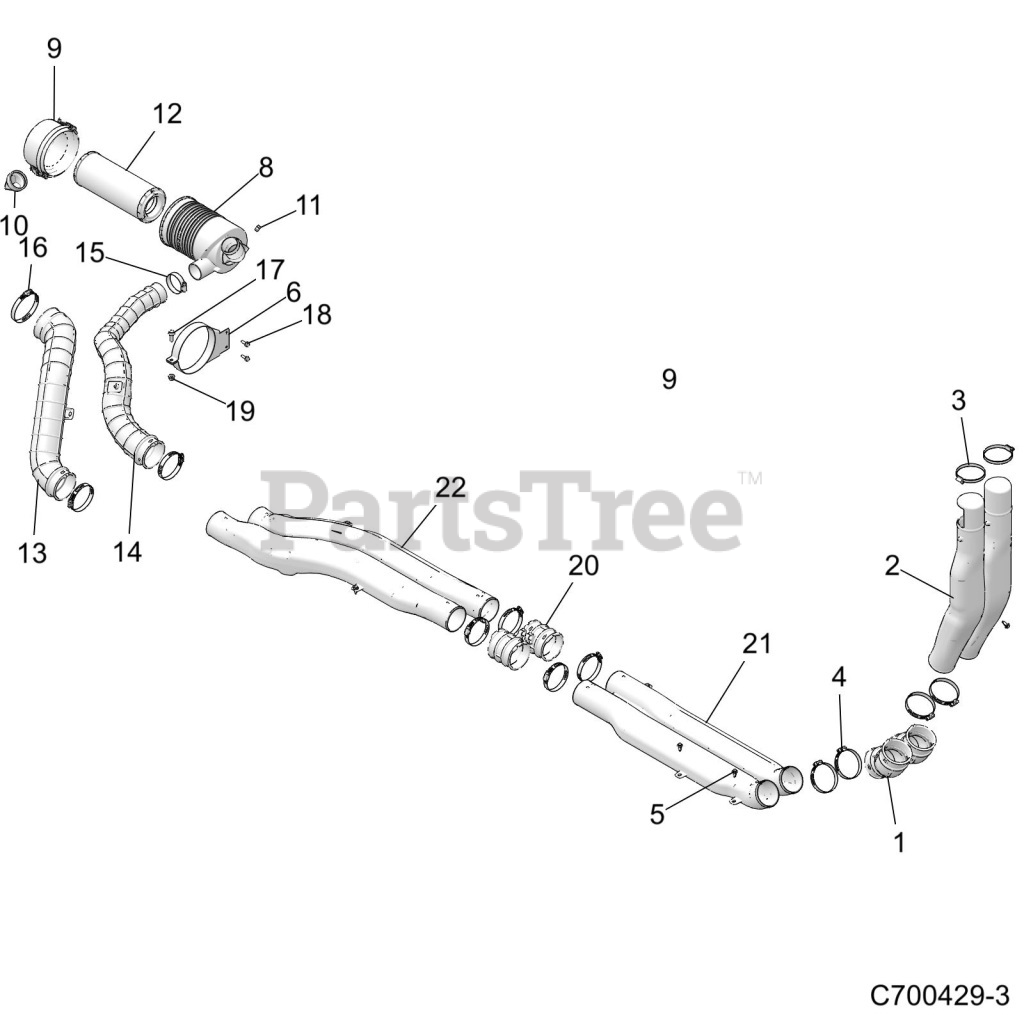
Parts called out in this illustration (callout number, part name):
1	HOSE-JOINT
2	DUCT-INTAKE,FRONT
3	CLAMP-BAND,NARROW 70-90MM
4	CLAMP-HOSE SLOTTED,75-90 DIA
5	RIVET-TUFLOK,.315-.325X.787 (5
6	WELD-MOUNT,AIRBOX
7	ASM-AIR INTAKE,ULTRAWEB
8	ASM., AIRBOX, MAIN
9	ASM-LID,AIRBOX
10	VALVE-AIRBOX
11	PLUG-AIRBOX
13	HOSE-CLUTCH INLET TO TUNNEL
14	HOSE-INTAKE,PRE-FILTER
15	CLAMP, HOSE, S.S.(10)
16	CLAMP-HOSE SLOTTED,89-100 DIA
17	BOLT-M8X1.25X25,HXFLG-OLIVE D
18	SCR-M6X1.0X20,HXHD,FLG,TDFM,BL
19	NUT-M8X1.25,FLG,NYLOC-OLIVE D
20	HOSE-INTAKE, DUCT
21	DUCT-TUNNEL, FRONT
22	DUCT-TUNNEL, REAR
